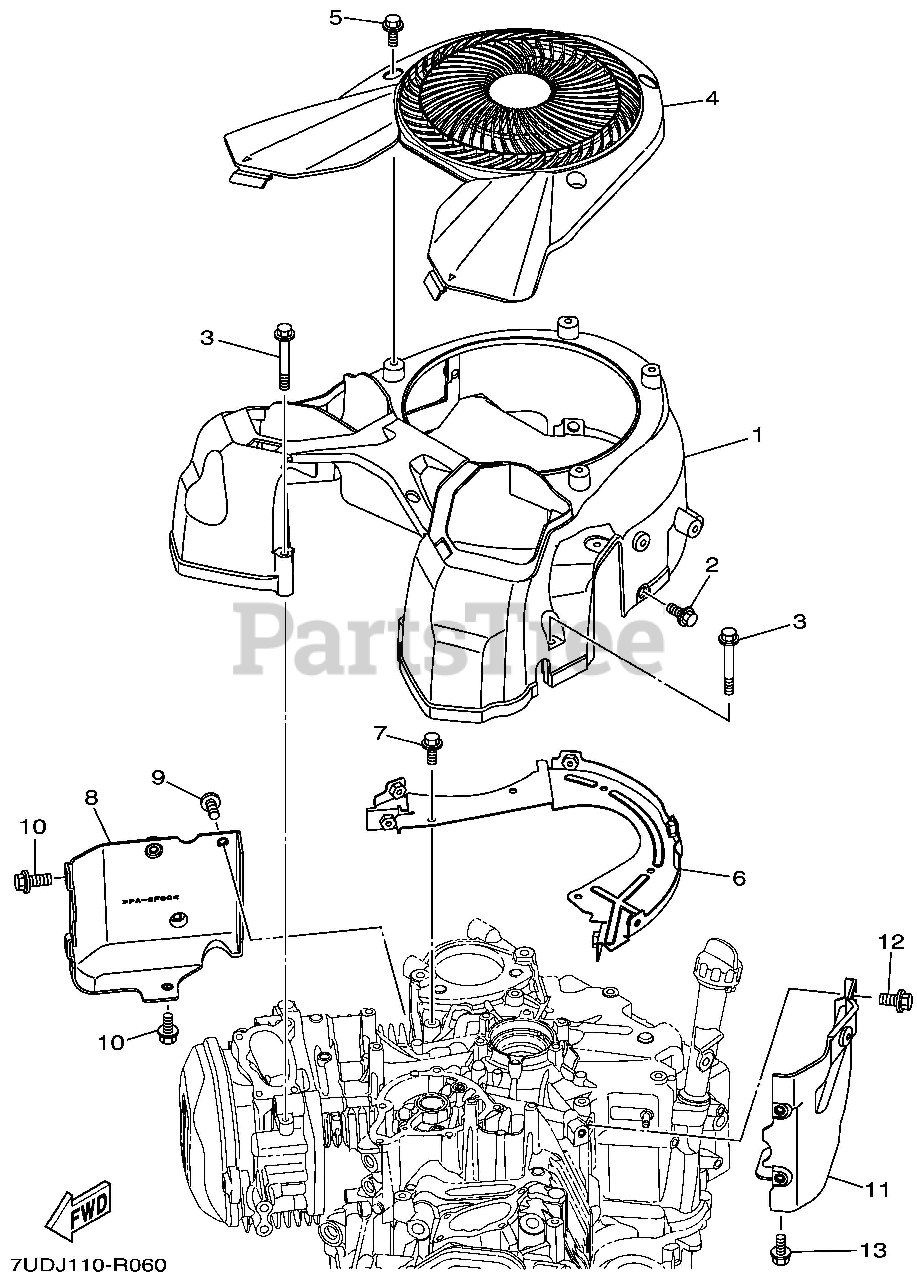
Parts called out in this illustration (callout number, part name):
1	CASE, FAN
3	BOLT, FLANGE
4	COVER, FAN CASE
6	SCROLL, AIR SHROUD
7	BOLT, FLANGE
8	AIR SHROUD, CYLINDER 1
9	BOLT, FLANGE
10	BOLT, FLANGE
11	AIR SHROUD, CYLINDER 3
12	BOLT, FLANGE
13	BOLT, FLANGE
